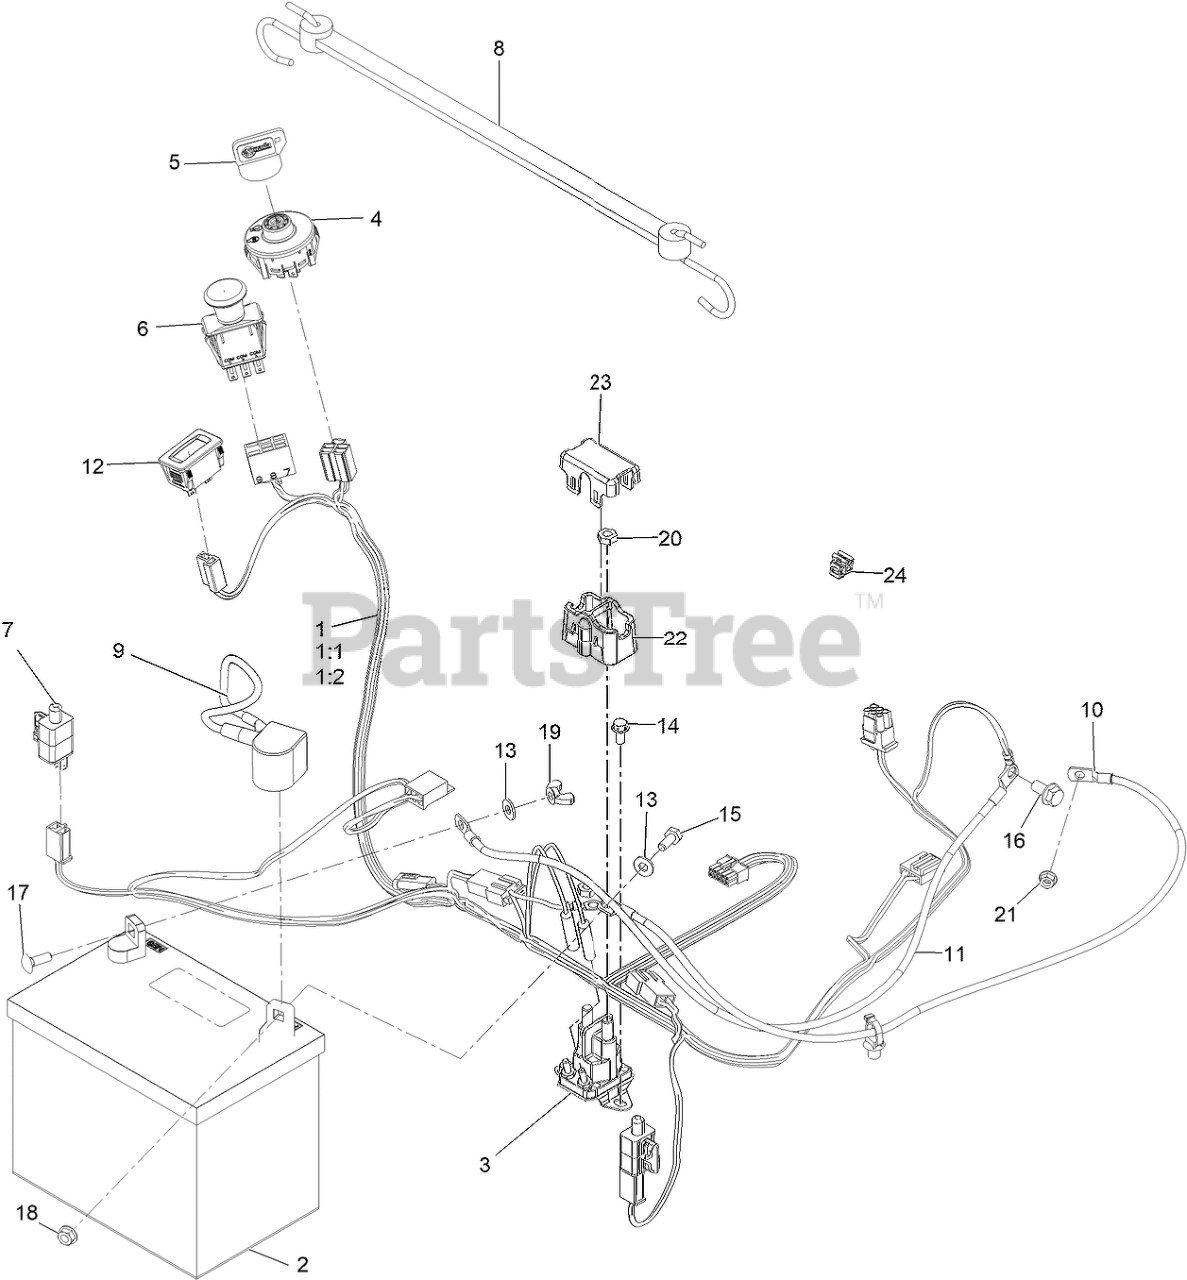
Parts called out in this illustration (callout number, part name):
1	HARNESS-WIRE
2	BATTERY
3	SOLENOID
4	SWITCH-IGNITION
5	KEY-IGNITION
6	SWITCH-PTO
8	STRAP-RUBBER
9	CABLE-BATTERY, POS
10	CABLE-BATTERY, RED (8 GAUGE)
11	CABLE-BATTERY, BLACK
12	HOURMETER
13	WASHER-FLAT
14	SCREW-HWH
15	SCREW-HH
16	SCREW-HHF
17	BOLT-CARR
19	NUT-WING
20	NUT-JAM
22	COVER-SOLENOID
23	CAP-SOLENOID
24	CLIP-HARNESS
